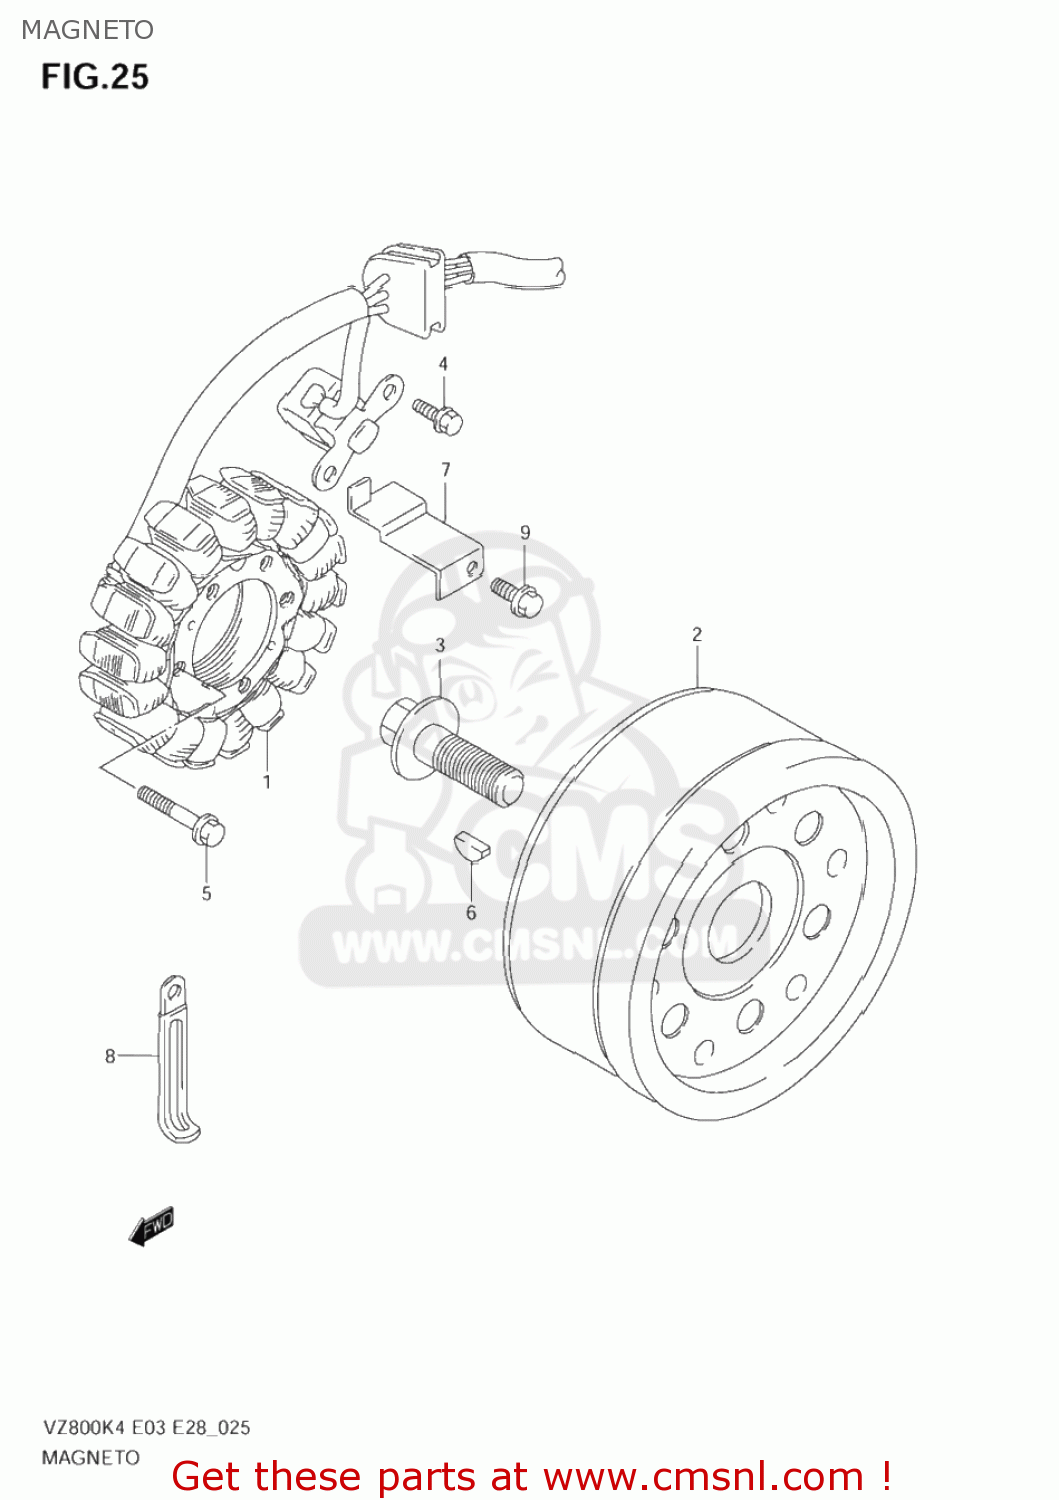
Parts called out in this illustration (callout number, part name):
1	STARTER ASSY
2	ROTOR ASSY
3	BOLT(14X43)
4	BOLT
5	BOLT,G/S SWITC
6	KEY
7	CLAMP,MAGNETO LEAD WIRE
8	CLAMP(L:45)
9	BOLT
